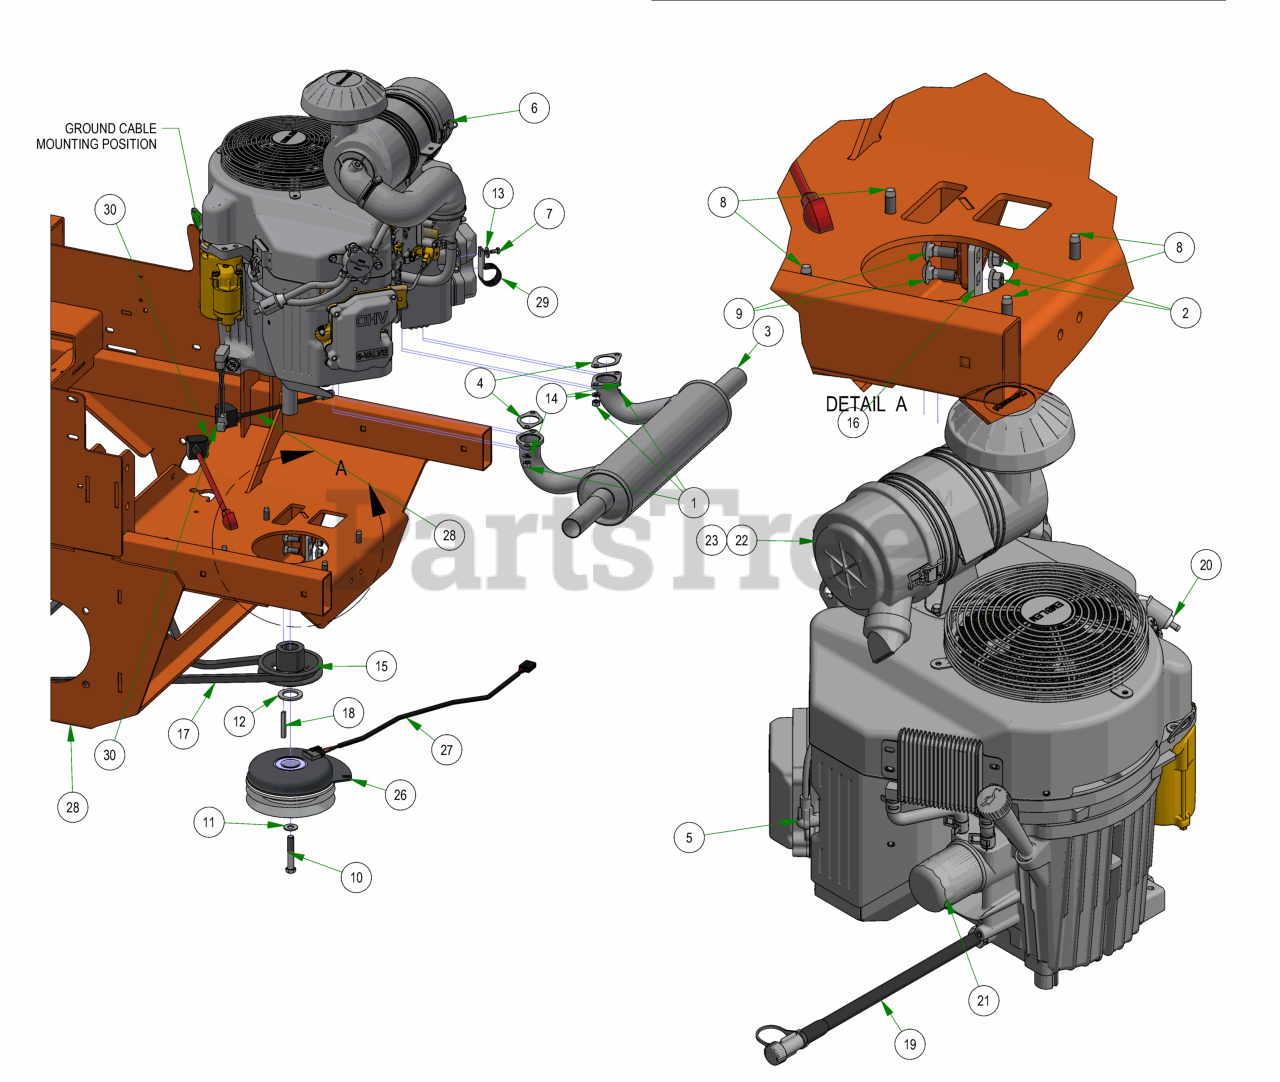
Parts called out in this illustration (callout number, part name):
1	M8-1.25 DIN 934 HEX NUT (CL.8) ZINC
2	3/8-16 NYLON INSERT FLANGE LOCKNUT (GR.F) ZINC
3	2019 Rebel/Rogue Kawasaki 1000 Muffler
4	Exhaust Gasket
5	Spark Plug - Kawasaki
6	Kawasaki FX1000 Engine
7	M6-1.0 X 12MM DIN 933 HEX TAP BOLT (CL 8.8) ZINC
8	3/8-16 X 1-1/8 HEX WASHER UNSLOT SERRATED (TRI-LOB) TRS ZINC YELLOW
9	3/8-16 X 1 CARRIAGE BOLT (GR.5) ZINC
10	7/16-20 X 2-1/2 HEX Bolt GR 8 W/ Patch
11	3/8 FLAT WASHER USS (1" OD) ZINC
12	1.140 ID X 1.750 OD X .132 THICK FLAT WASHER PLAIN
13	1/4 USS FLAT WASHER (3/4 OD) ZINC
14	5/16 SPLIT LOCKWASHER ZINC
15	4 3/4 Motor Pulley
16	Rebel Clutch Tab
17	2019 Rebel Pump Belt
18	1/4 X 2 SQ MACHINERY KEY 1018 STL PLAIN
19	Kawasaki Oil Drain
20	Universal Inline Fuel Filter
21	Oil Filter
22	Canister Air Filter- Outer
23	Canister Air Filter- Inner
26	Clutch Assembly
27	Clutch Pigtail
28	2023 Rebel Frame - Painted
29	Diesel Hydraulic Hose Clamp
29	Starter Cable
30	2019 Harness Adaptor-Gen2 FX-ALL
30	14" Red Battery Cable
